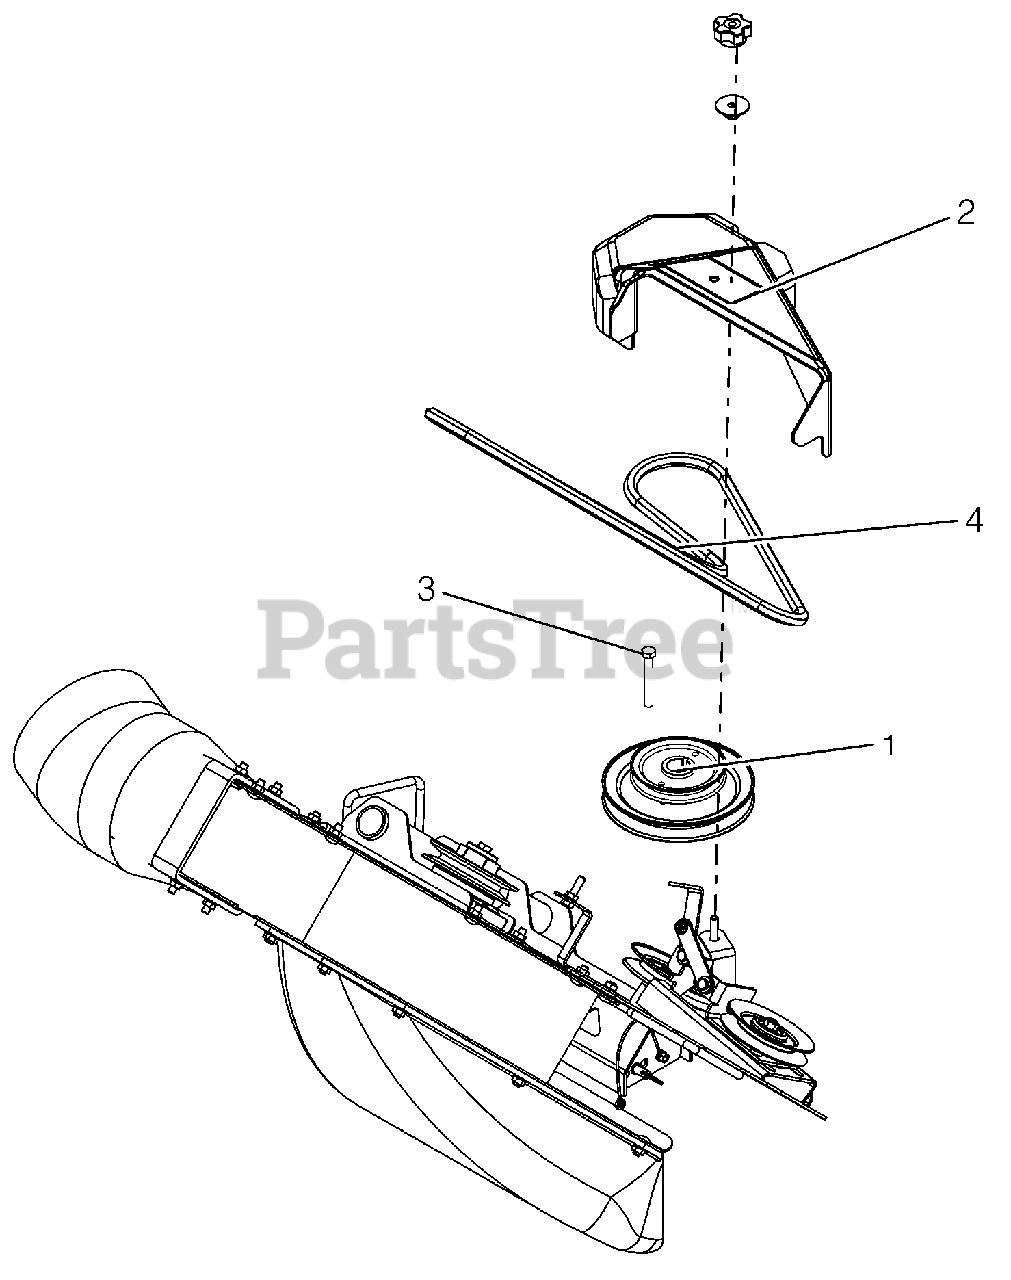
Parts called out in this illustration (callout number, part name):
1	PULLEY, DBL-1"IDX6.75"&4.25"OD
2	COVER- BELT 52" BLOWER
3	BLT, HEX-FLG .25-20X.75 G5 ZZC
4	HEX BELT- HAA-WRAPPED
